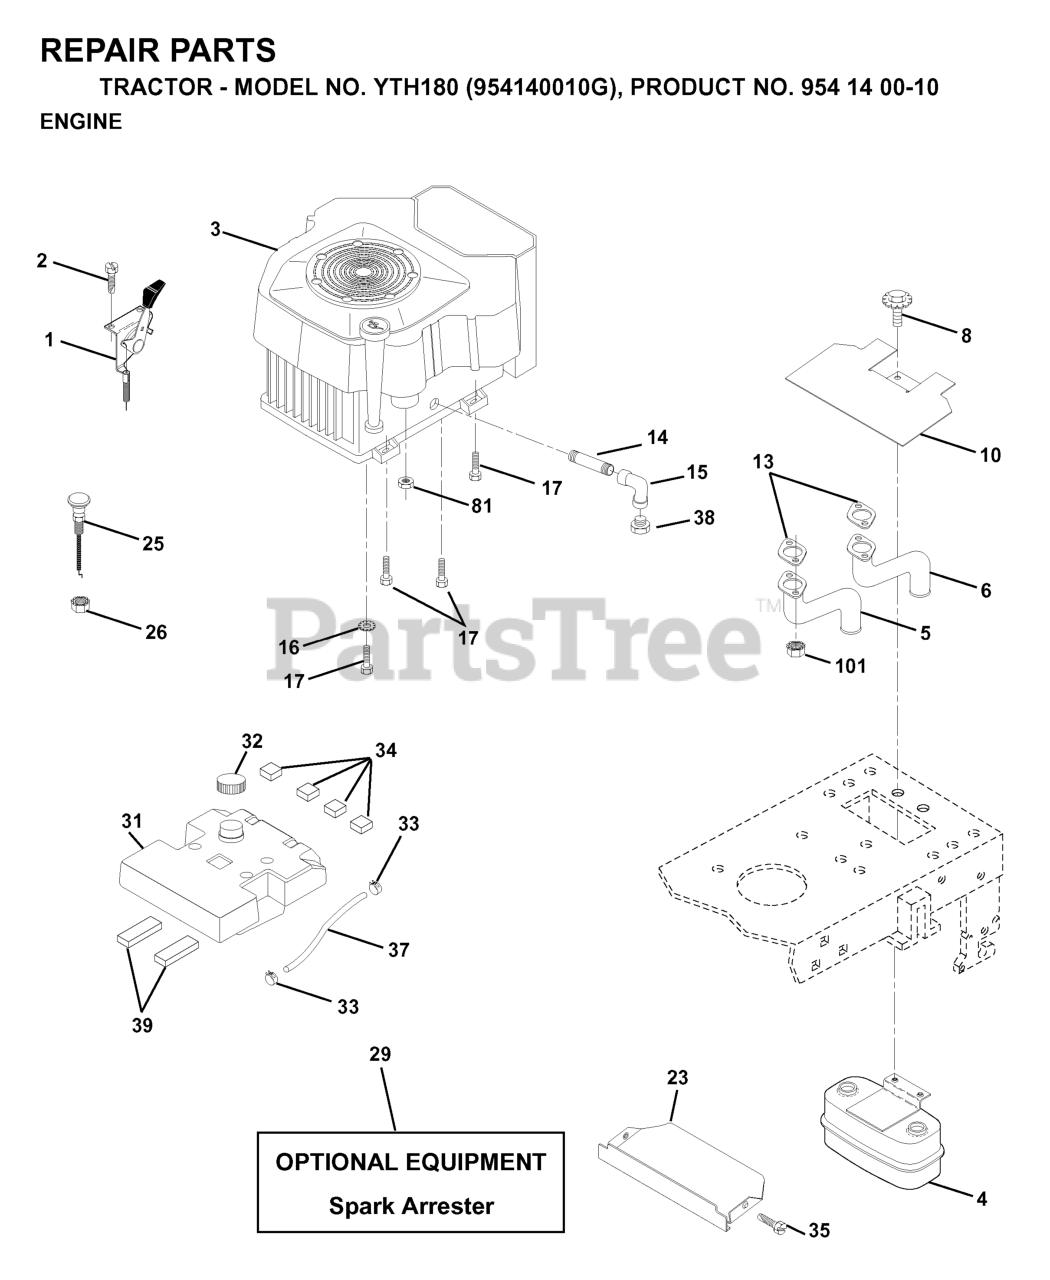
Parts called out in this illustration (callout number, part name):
1	CONTROL THROTTLE
2	SCREW LT
4	MUFFLER.TWIN.CYL.LOW.TONE
5	RP.PIPE-EXHAUST LH
6	RP.PIPE-EXHAUST RH
8	BOLT HEX WASHER HD 5/16-18
10	RP SHIELD HEAT MUFFLER
14	Nipple, Pipe 3/8 NPT x 4-1/2
15	ELBOW
16	LOCKWASHER
17	SCREW LT
25	CONTROL, CHOKE
26	Nut Keps 3/8 - 24 UNF
29	KIT.SPARK ARRESTOR 794945 B&S
31	TANK.FUEL(3.5.GAL)
32	FUEL CAP
33	HOSE CLAMP
34	PAD-SPACER LT
35	SCREW.THDROL.5/16-18X3/4.TTY
37	HOSE T
39	PAD IDLER TI
81	NUT FLANGE 1/4-20 STARTER NUT
101	FLANGE NUT
